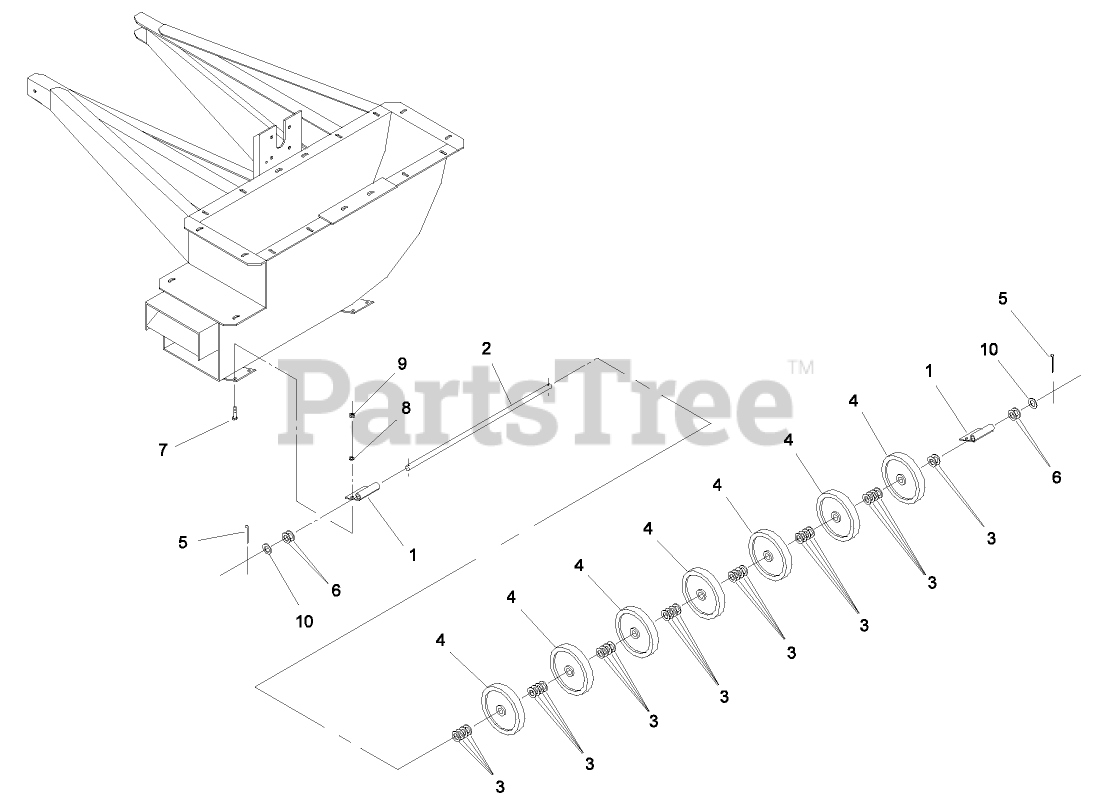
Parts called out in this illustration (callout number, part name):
1	ROLLER BRACKET R
2	ROLLER AXLE
4	WHEEL BLACK PLASTIC
5	PIN-COTTER
6	MACHINERY BUSHING
7	SCREW-HH
8	WASHER-LOCK
9	NUT-HEX
10	MACH. BUSHING 3/4-18GA
